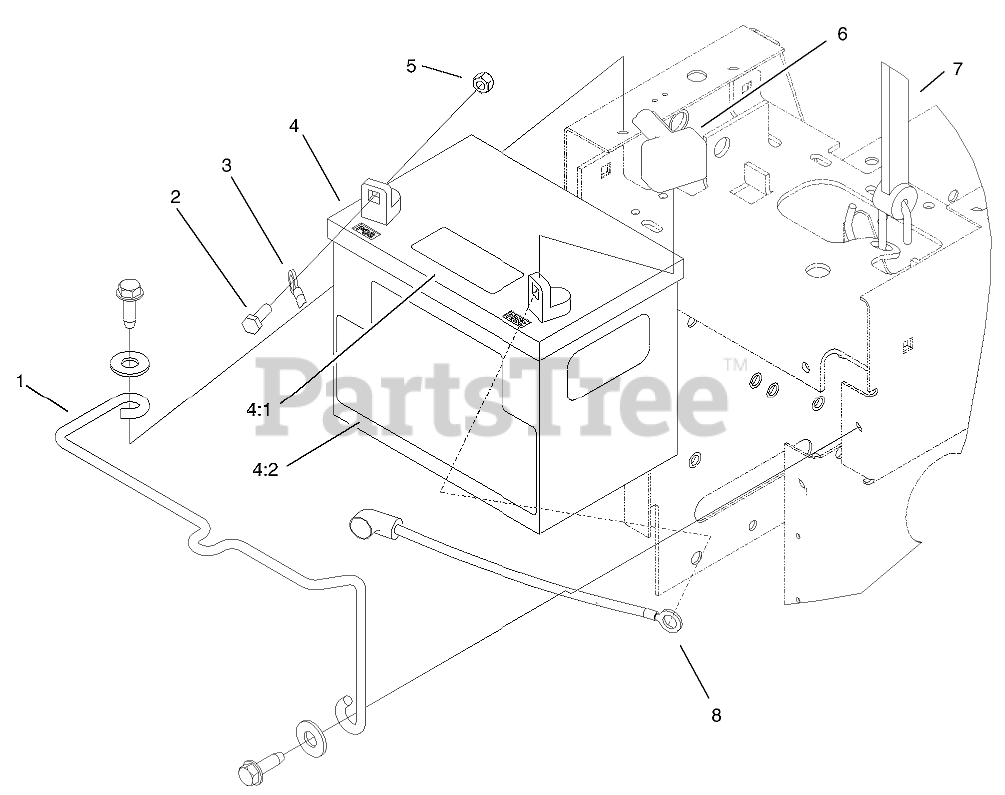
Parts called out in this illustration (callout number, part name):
1	ROD-BATTERY
2	SCREW-HH
3	CABLE-NEGATIVE, BLACK
4	BATTERY
4:1	Decal-Battery
4:2	Decal-Battery
5	NUT-LOCK, NI
6	BOOT-TERMINAL
7	HOLDDOWN-BATTERY
8	CABLE-BATTERY, POSITIVE
